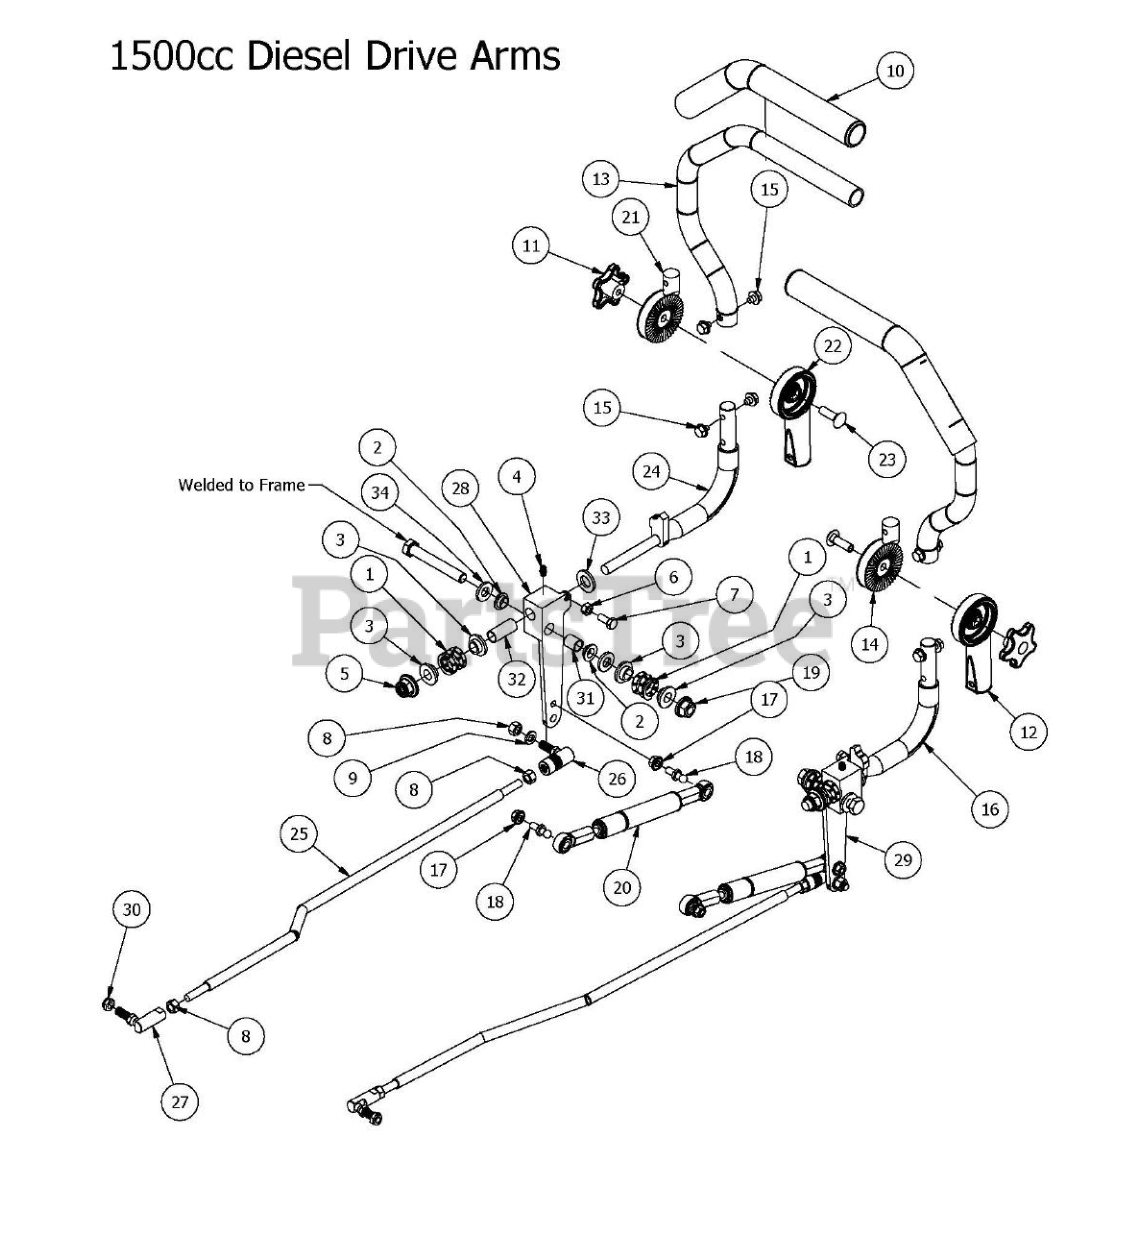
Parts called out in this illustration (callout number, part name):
1	Drive Lever Spring
2	Bushing for 2012 Drive Arms
3	.515 ID Nylon Shoulder Washer
4	1/4" Press in Grease Fitting
5	1/2-13 Nylon Flange Nut
7	5/16" x 3/4" Hex Bolt
8	3/8" Fine Threaded Jam Nut
9	3/8" Lock Washer
10	Black Steering Grip
11	Black Knob for Adjustable Steering Arm
12	Lower Adjuster -Steering Arm- Right
13	Upper Tube-Adjustable Steering
14	Upper Adjust Steering Arm- Right
15	5/16-18 1/2 HWH Bolt-Steering
16	Steering Arm Elbow - Right
17	5/16" Flange Nut
18	10mm Damper Ball Stud-Steering
19	1/2-13 Hex Flange Nut ZC
20	Steering Damper
21	Upper adjuster-Steering Arm- Left
22	Lower Adjuster - Steering Arm- Left
23	3/8" x 1 1/4" Carriage Bolt
24	Steering Arm Elbow - Left
25	1500cc Diesel Push Rod
26	Quick Release Ball Joint
27	3/8-24 Ball Joint
28	Drive Arm Lever Housing (Left)
29	Drive Arm Lever Housing Right
30	3/8-24 Nylon Insert jam locknut
31	Drive Arm Block Insert-short
32	Drive Arm Block Insert-long
33	.630 ID Plastic Washer
34	.505x1x.125 Oil Impregnated washer
